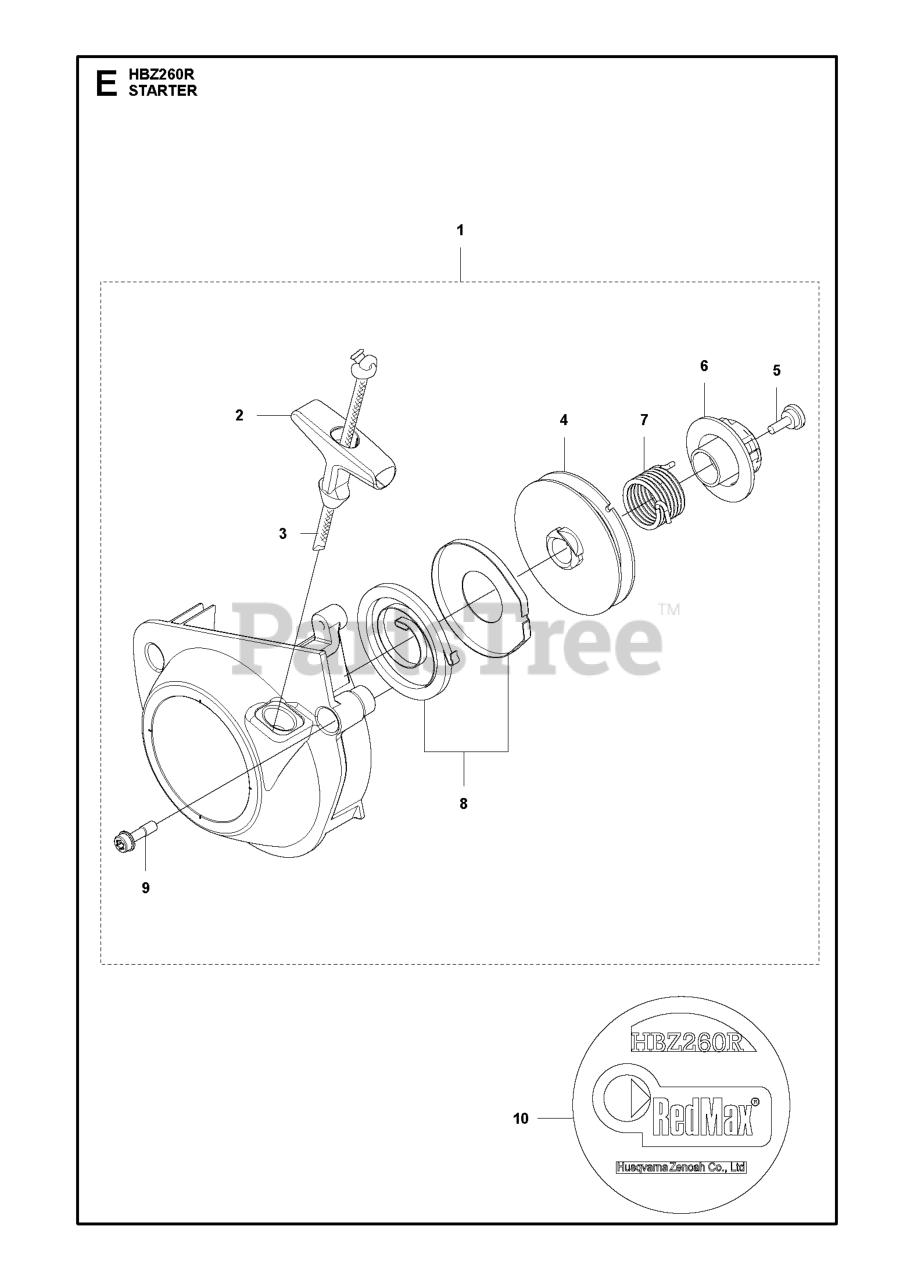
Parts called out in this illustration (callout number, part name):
1	STARTER ASSY
2	STARTER HANDLE
6	CAM PLATE
7	SPRING DAMPER
8	SPRING ASSY
9	BOLT M5 X 16
10	DECAL BRAND HBZ260R
